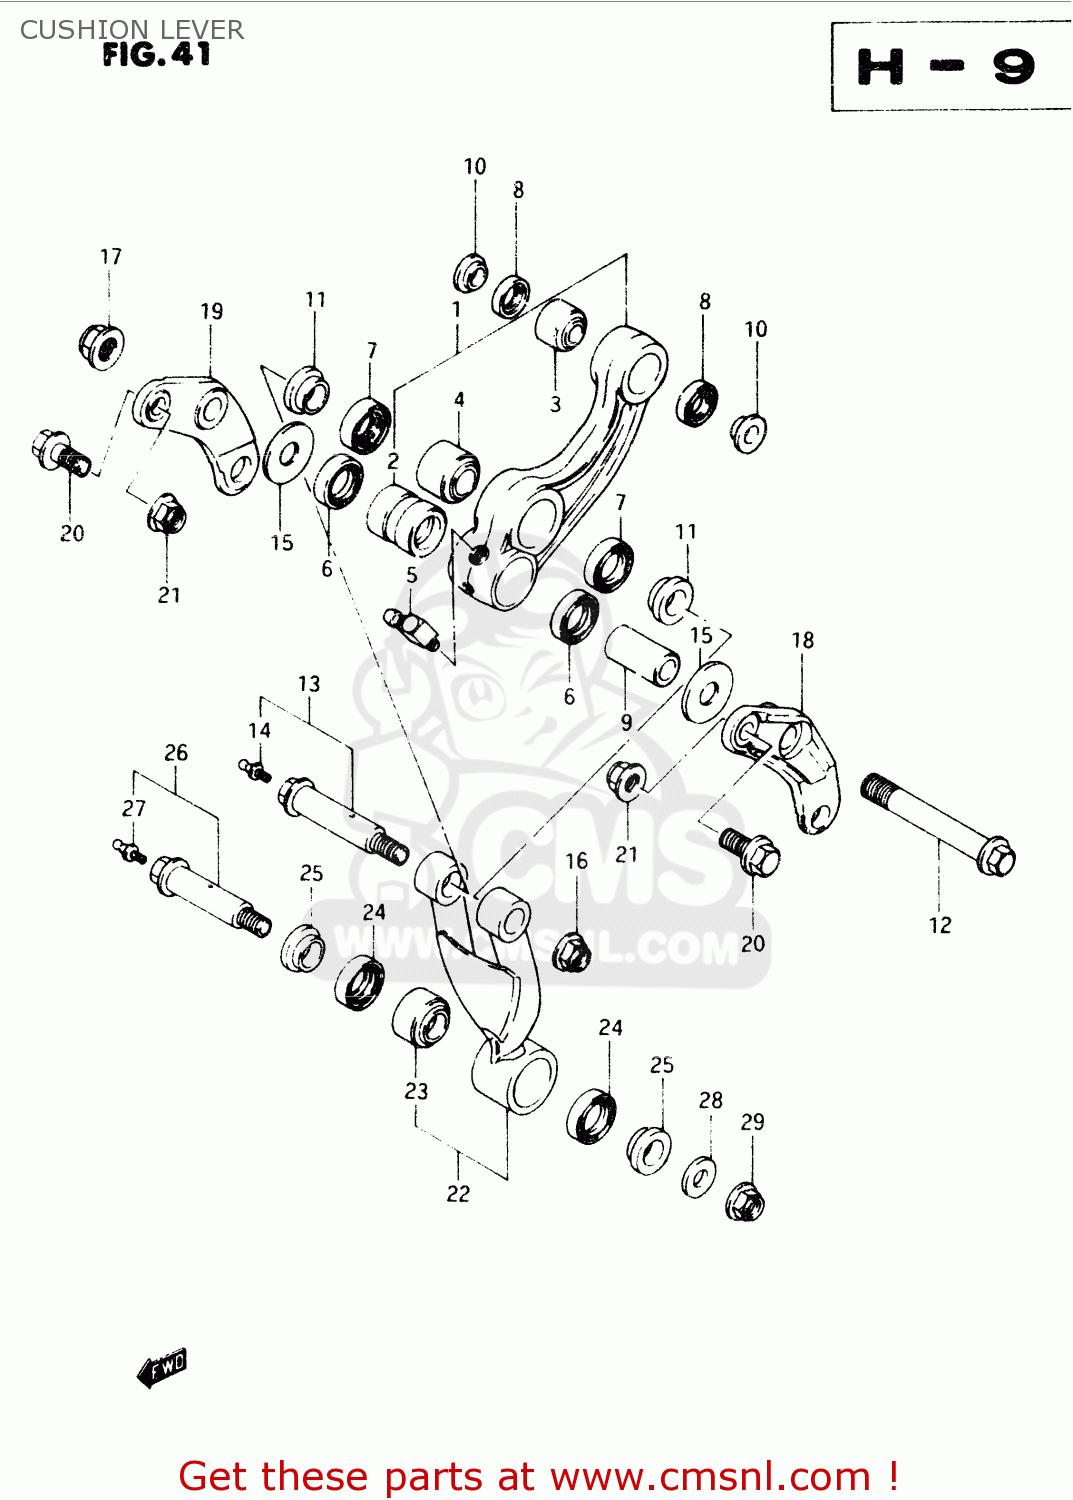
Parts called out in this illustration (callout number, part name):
1	LEVER SET, CUSHION
2	BUSHING,LEVER(20X26X26)
3	BEARING(10X24X15)
4	BEARING(15X29X18)
5	NIPPLE
6	SEAL,RR CUSHION FR DUST
7	DUST SEAL,CTR
8	DUST SEAL,RR CUSHION LEVER RR
9	SPACER,RR CUSHION LEVER FR
10	SPACER
11	SPACER
12	BOLT,RR CUSHION LEVER FR
13	BOLT SET,CUSHION LEVER CTR
14	NIPPLE
15	WASHER, FRONT
16	NUT
17	NUT 12MM
18	HOLDER,RR CUSHION LEVER,L
19	HOLDER,RR CUSHION LEVER,R
20	BOLT(10X25)
21	NUT
22	ROD SET,LEVER
23	BEARING(15X29X18)
24	DUST SEAL,CTR
25	SPACER
26	BOLT SET,CUSHION ROD LWR
27	NIPPLE
28	WASHER(10.1X25X3.2)
29	NUT
